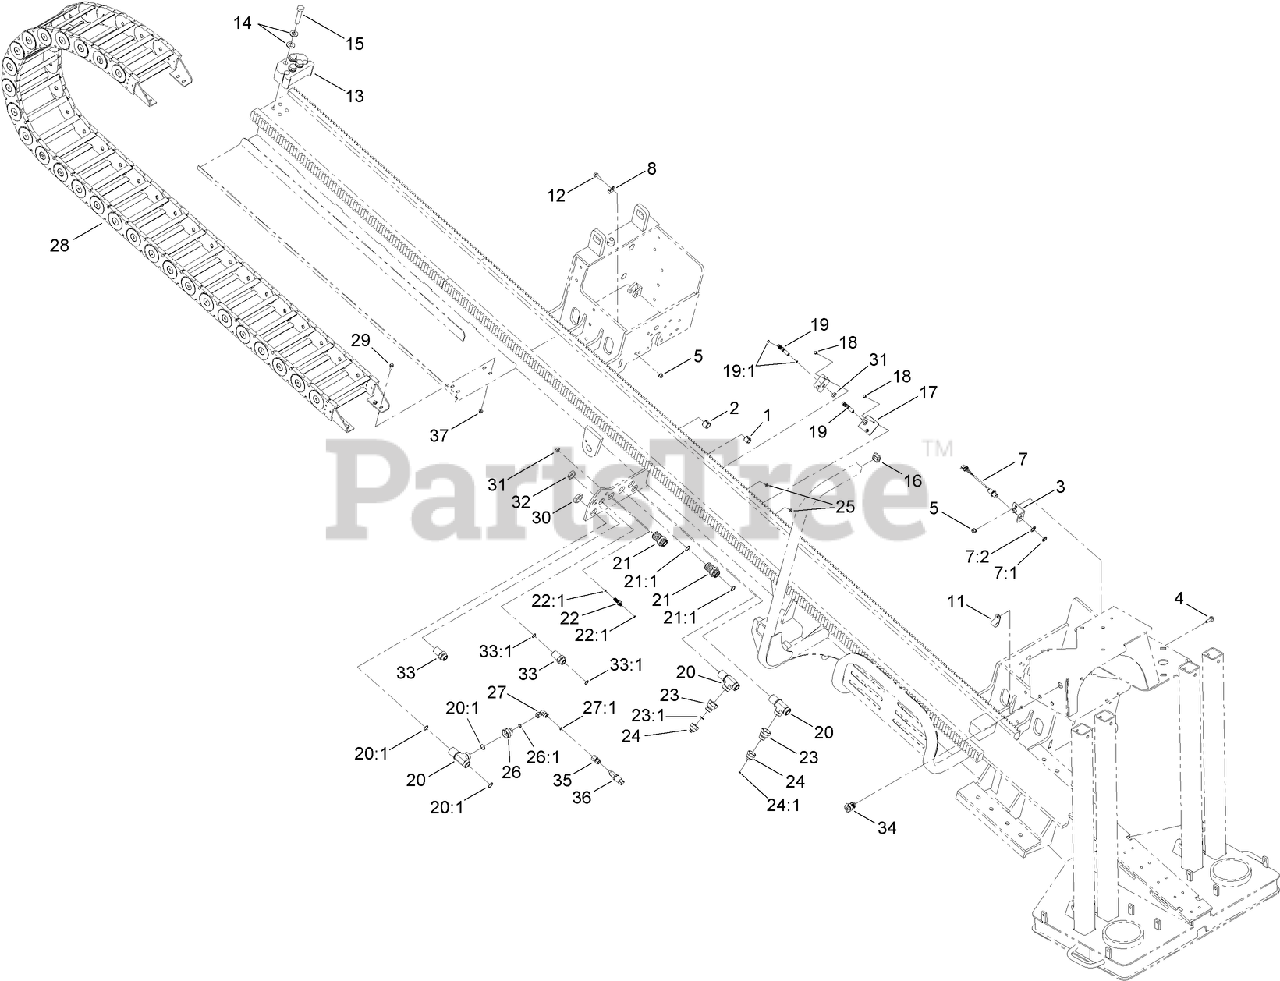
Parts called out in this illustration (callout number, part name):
1	BUSHING-SPRING
2	BUSHING-SPRING
3	BRACKET-SWITCH
4	SCREW-HHF
5	NUT-LOCK, NI
7	PROXIMITY SWITCH ASM
7:1	NUT-HEX
7:2	WASHER-LOCK, INTERNAL TOOTH
8	R-CLAMP
11	CLAMP-R
12	SCREW-HHF
13	STOP-CARRIAGE, REAR FRAME
15	SCREW-HH
16	CAP-SQUARE, PLASTIC
17	PLATE-MOUNT
18	SCREW-HHF
19	FITTING-TEE
19:1	O-RING
20	FITTING-TEE, BULKHEAD
20:1	O-RING
21	ADAPTER-HYD
21:1	O-RING
22	UNION-BULKHEAD
22:1	O-RING
23	FITTING-REDUCER
23:1	O-RING
24	FITTING-REDUCER
24:1	O-RING
25	NUT-FLANGE, NI
26	FITTING-REDUCER
26:1	O-RING
27	FITTING-HYD
27:1	O-RING
28	CARRIER-HOSE, 36 LINKS
29	SCREW-HHF
30	NUT-BULKHEAD
31	NUT-LOCK
32	NUT-BULKHEAD
33	FITTING-HYD
33:1	O-RING
34	RECEPTACLE-12V
35	FITTING-STRAIGHT
36	TRANSDUCER (W/ISOLATOR)
37	NUT-LOCK, HHF
